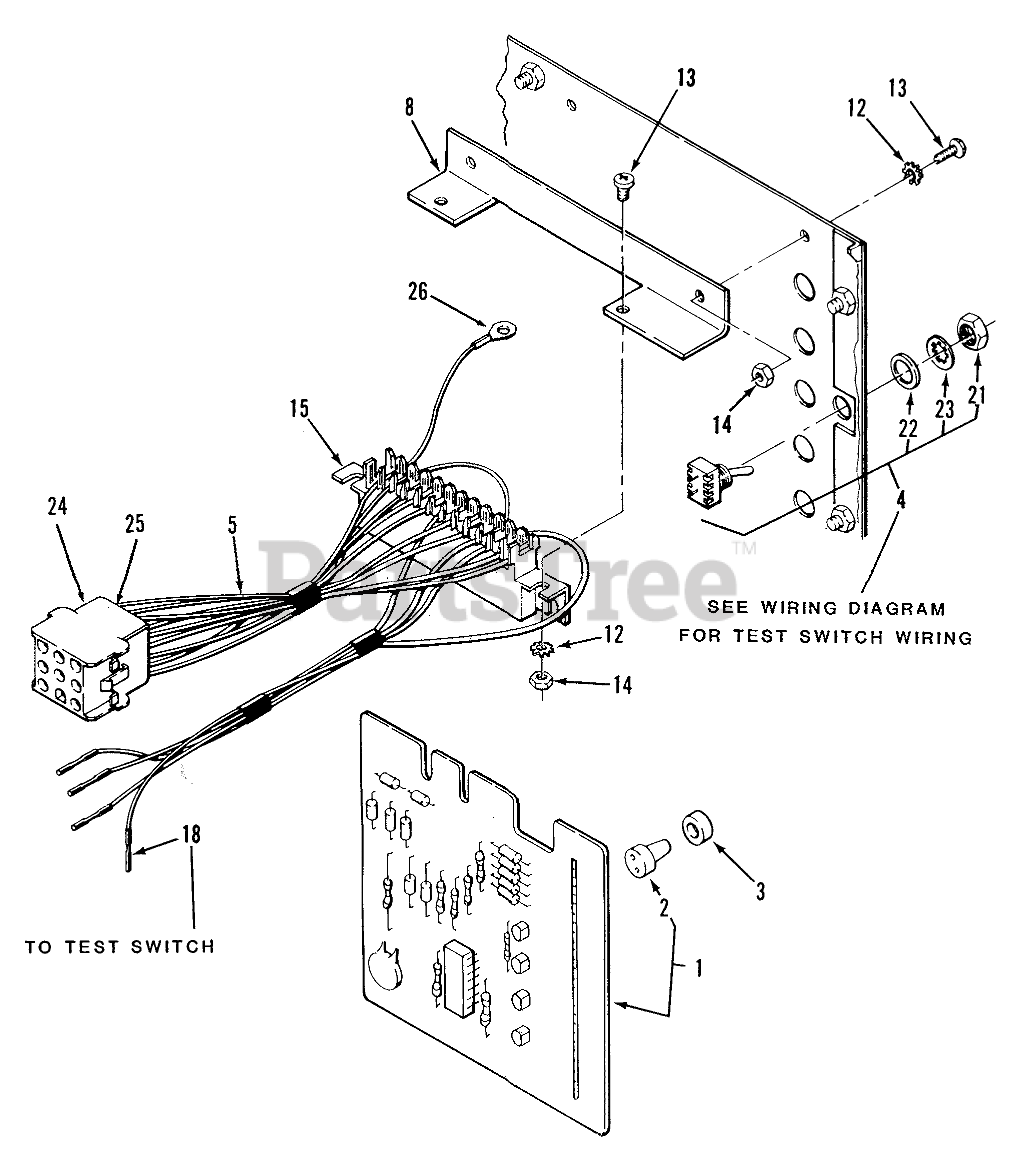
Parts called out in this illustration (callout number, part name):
1	P.C Board (Includes item 2)
2	LIGHT INDICATOR
3	ASSY LENS & BUSHING
4	SWITCH TOGGLE
5	P.C. BOARD HARNESS
8	BRACKET
12	Washer-Lock
13	SCREW
14	Nut
15	Molex Connector (Part of 6)
18	062 X 031 TAB RECEPT
21	NUT F/W 116796
22	RING LOCKING
23	Washer
24	9-CIRCUIT CAP
25	TERMINAL - SOCKET
26	No. 6 Ring Terminal
